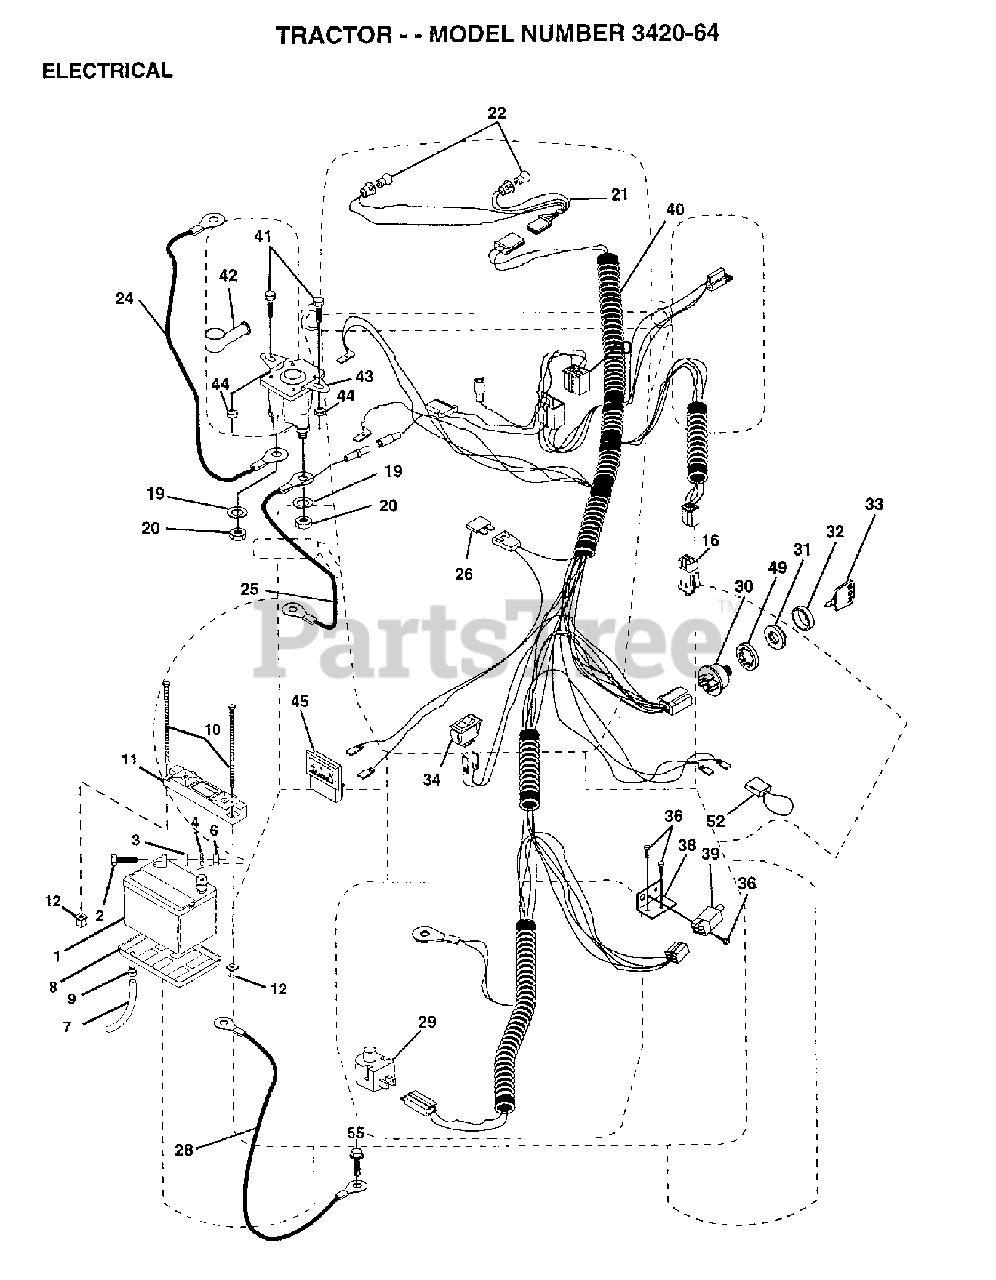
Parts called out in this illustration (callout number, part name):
1	BATTERY
2	BOLT.HEX.1/4.X.3/4.DICHROMATE
3	WASHER
4	LOCKWASHER
6	NUT
7	BATT DRAIN TUBE T
8	TRAY.BATTERY
9	HOSE CLAMP T
10	BOLT 1/4-20 X 7.5
20	NUT
22	LIGHTBULB
24	CABLE BATTERY 6 GA 22" W/16W
25	BATTERY CABLE
26	FUSE *
28	CABLE GROUND 6 GA 21" 90T BLK
29	SWITCH SEAT
30	Ignition Switch Kit
31	NUT, IGNITION
32	COVER KEY IGNITIO
33	KEY MLD GEN DELTA
34	SWITCH LT
39	SWITCH INTERLOCKT
41	BOLT
42	TERMINAL COVER
43	Solenoid Kit, .95
44	NUT.HEX.KEPS.1/4-20
45	AMMETER
52	WIRE PROTECTION LOOP
55	SCREW LT
70	HARNESS, ENGINE
